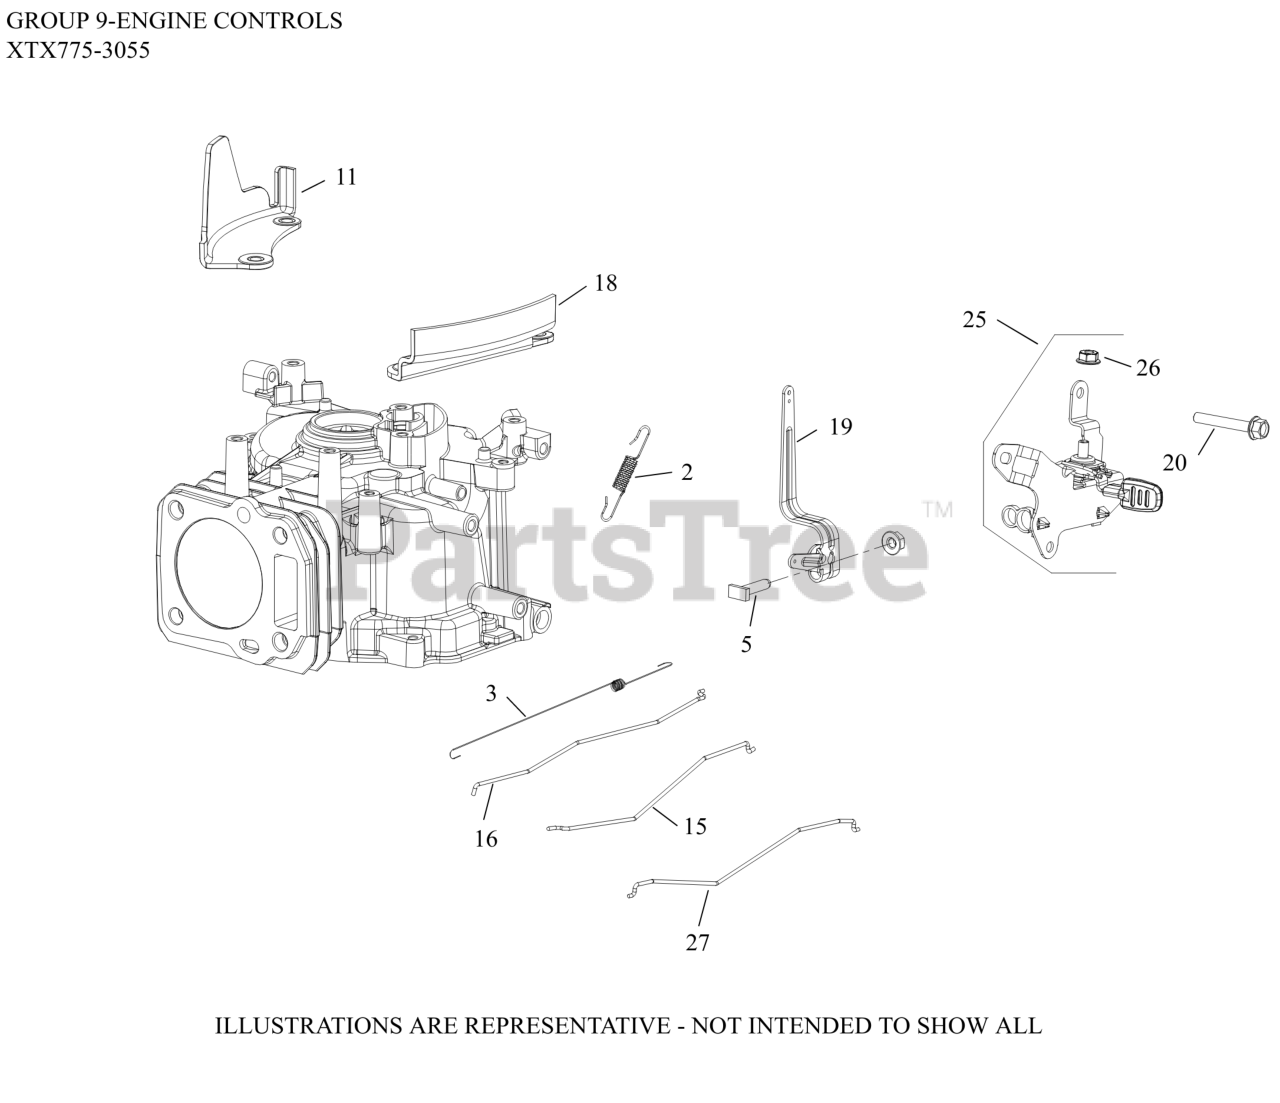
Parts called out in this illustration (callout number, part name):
2	SPRING, GOVERNOR
3	SPRING, LINKAGE
5	SCREW, RECTANGLE HEAD (M6)
11	GUARD, FINGER
16	LINKAGE, GOVERNOR
18	GUARD, FINGER
19	LEVER, GOVERNOR
20	SCREW, HEX FLANGE (M6)
25	CNTRL ASSY,NON-REMOTE MAN CHOKE
26	NUT, HEX FLANGE LOCK (M6)
27	LINKAGE, CHOKE
